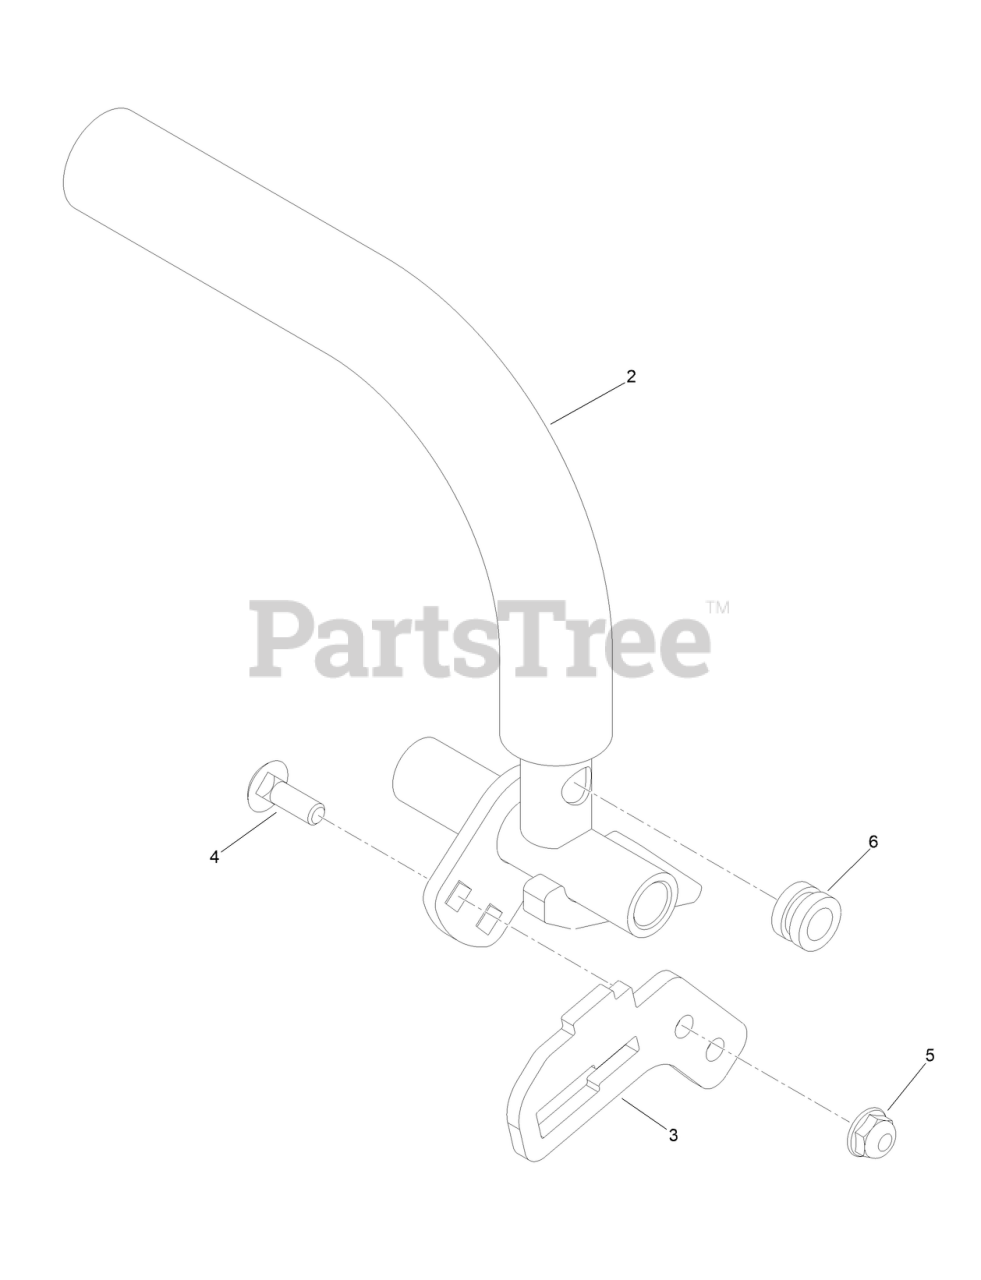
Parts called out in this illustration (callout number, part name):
2	GRIP-CONTROL, MOTION
3	PLATE-ROD, CONTROL
4	BOLT-CARR
6	Grommet-Rubber
